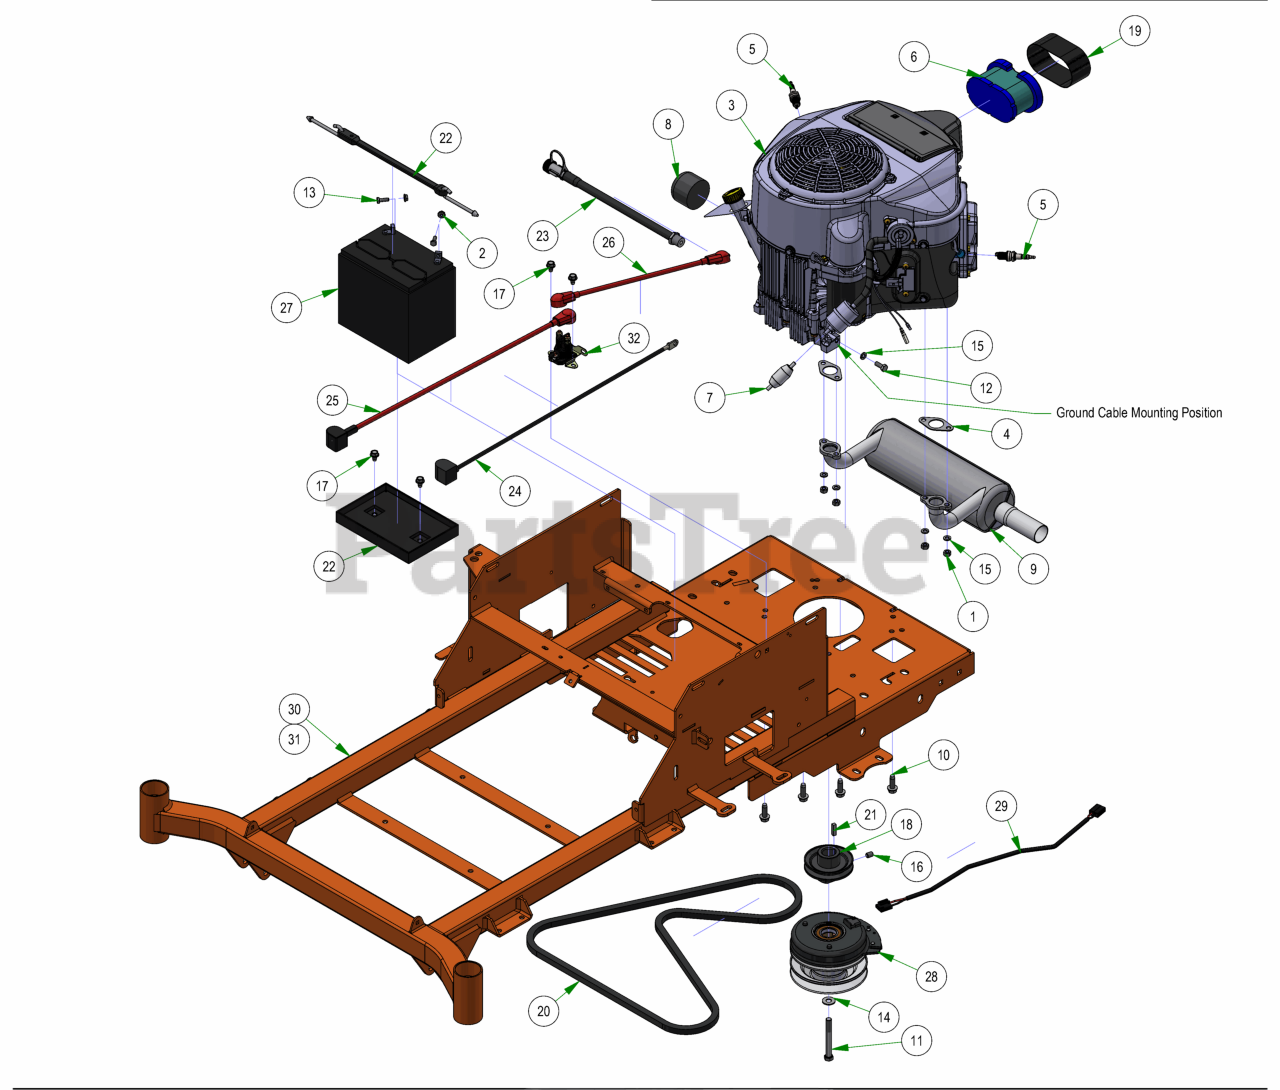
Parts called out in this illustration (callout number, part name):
1	M8-1.25 DIN 934 HEX NUT (CL.8) ZINC
2	1/4-20 HEX SERRATED FLANGE NUT HARD/ZINC
3	726cc Kawasaki Engine-FR651V
4	Exhaust Gasket
5	Spark Plug - Kawasaki
6	Kawasaki Air Filter
7	Universal Inline Fuel Filter
8	Oil Filter
9	Kawasaki Muffler 1251
10	3/8-16 X 1-1/8 HEX WASHER UNSLOT SERRATED (TRI-LOB) TRS ZINC YELLOW
11	7/16-20 x 3 1/2" Hex Bolt GR8 W/ Patch
12	M8-1.25 X 20MM DIN 933 HEX TAP BOLT (CL 8.8) ZINC
13	1/4-20 X 3/4 HEX CAP SCREW (GR.5) ZINC
14	3/8 FLAT WASHER USS (1" OD) ZINC
15	5/16 SPLIT LOCKWASHER ZINC
16	3/8-16 X 1/2 SOCKET SET SCREW (CUP PT) PLAIN
17	5/16-18 X 1/2 HWH unslot (F) tcs zinc
18	3-3/4" Motor Pulley
19	Air Filter Pre-Cleaner for KAW
21	1/4 X 1 SQ MACHINERY KEY 1018 STL PLN
22	2023 Battery Hold Down Assembly
23	Kawasaki Oil Drain
24	24 inch Black Cable – MZ/ZT
25	24" Red Battery Cable
26	14" Red Battery Cable
27	SP-35 Battery
28	105 Ft Lb. Clutch - 1" Shaft
29	Clutch Pigtail
30	2025 MZ 42-48 Frame
31	2025 MZ-Avenger 54-60 Frame
